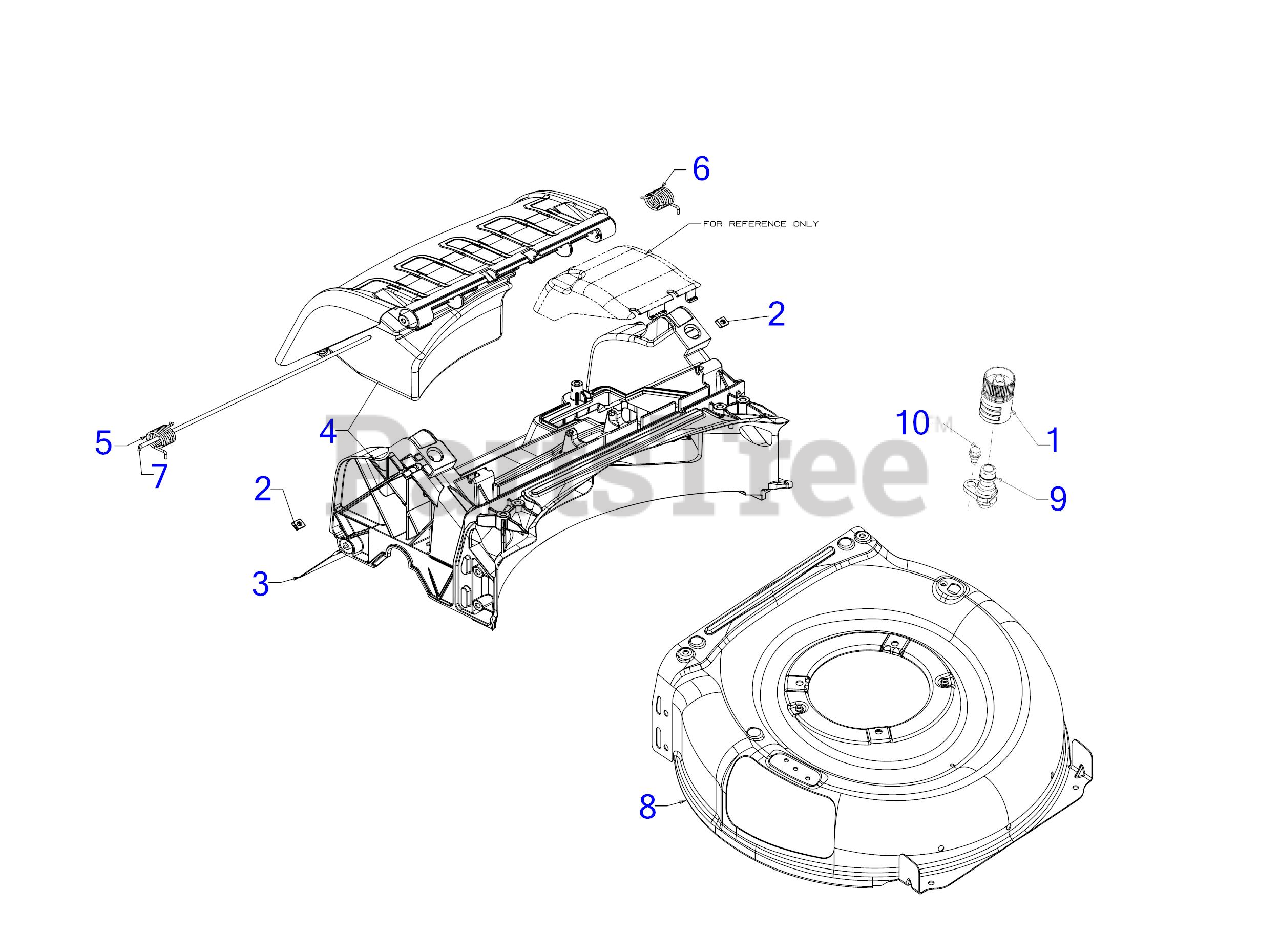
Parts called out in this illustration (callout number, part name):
1	WATER NOZZLE
2	SQUARE NUT 1/4-20
3	TRAILSHIELD
4	REAR BAG BAFFLE ASSEMBLY
5	TORSION SPRING (RH)
6	TORSION SPRING (LH)
7	REAR DOOR PIVOT ROD
8	21" DECK ASSEMBLY
9	DECK WASH NOZZLE
10	SHOULDER SCREW 1/4-20 x .50
